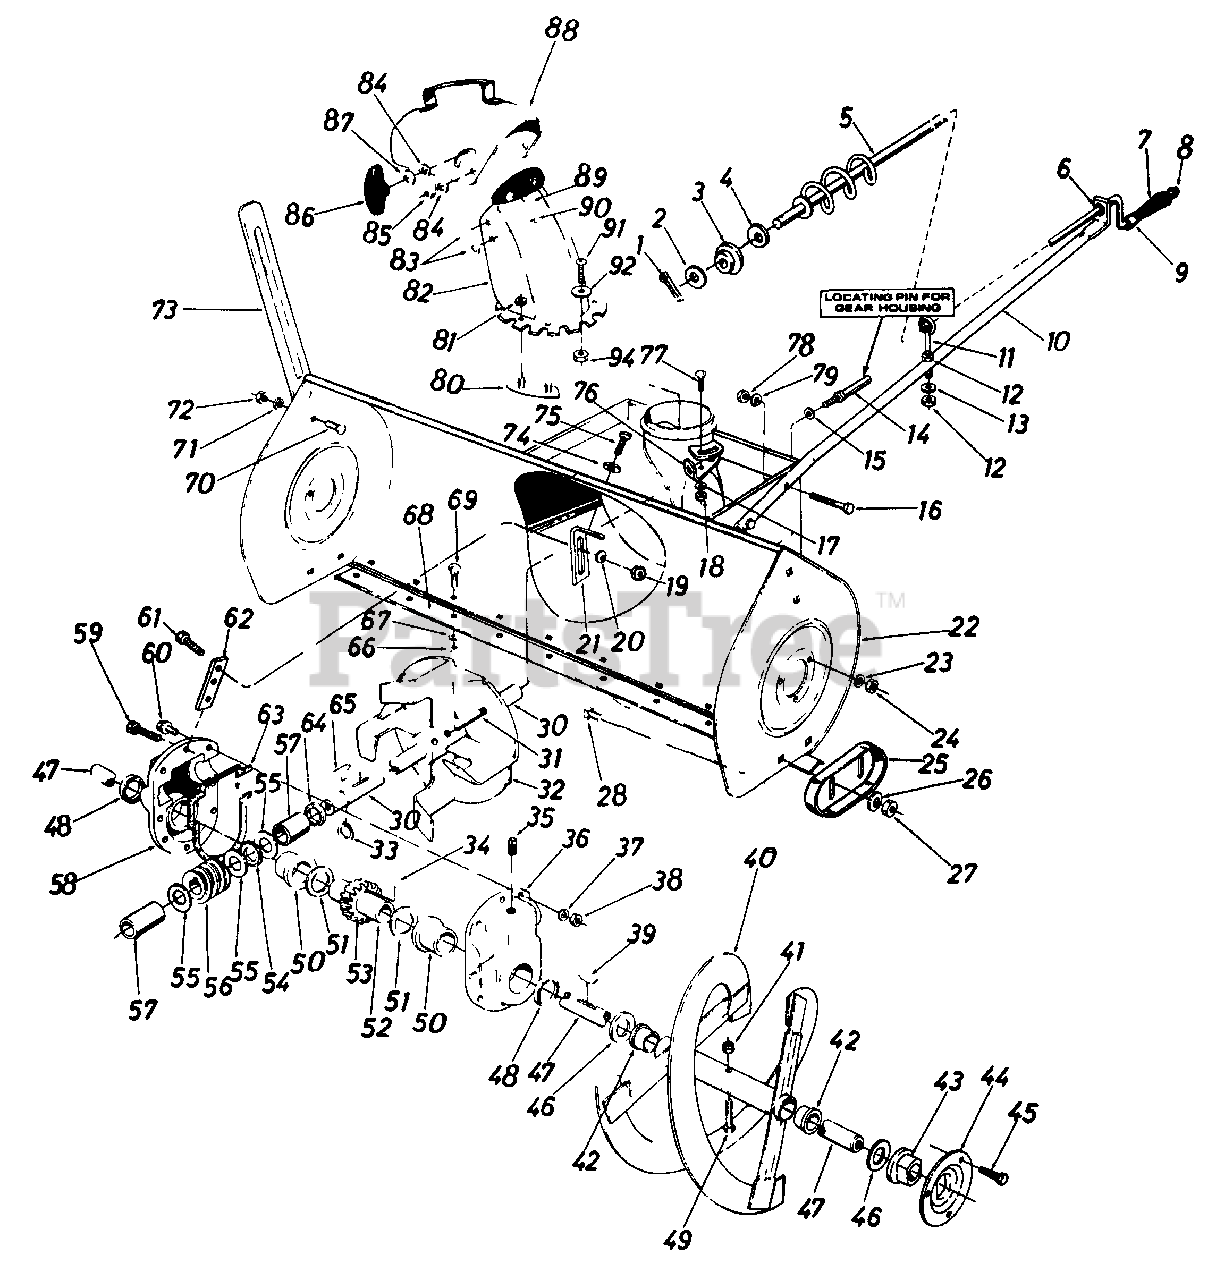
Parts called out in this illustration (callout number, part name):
1	Cotter Pin
2	Fl.-Wash. .39" I.D. x .62" O.D.
3	Plastic Bushing
4	Fl.-Wash. .385 I.D. x .62" O.D.
5	Chute Crank Ass'y.
6	Plastic Bushing
7	Knob Ball 3/8 Dia. Hole
8	Push Nut 3/8" Rod
9	Spacer .385 1. D. x .50" 1. D.
10	Chute Crank Support Tubing
11	Eyebolt
12	Hex Nut 5/16-18 Thd.*
13	Bell. Wash. .345" I.D. x .88" O.D.
14	Stud 3/8-16 x 2.75" Lg.
15	Bell.-Wash. .400" I.D. x .88" O.D.
16	Hex Bolt 3/8-24 x 1.25" Lg.*
17	Bell.-Wash. .345" I.D. x .88" O.D.
18	Hex Nut 5/16-18 Thd.*
19	Hex Nut 1/4-28 Thd.
20	Bell.-Wash. .265" I.D. x .75" O.D.
21	Gear Housing Support Brkt.
22	45 " Snow Blower Housing Ass'y.
23	L.-Wash. 5/16" I.D. *
24	Hex Nut 5/16-18 Thd.*
25	Slide Shoe
26	Bell .-Wash. .400" I . D. x .88 " O.D.
27	Hex Jam Nut 3/8-16 Thd.
28	Carriage Bolt 3/8-16 x .62" Lg.*
30	Blower Axle .875" Dia. x 14.75" Lg.
31	Spring Pin Spir. 5/16" Dia. x 1.75" Lg.
32	Blower Fan Ass'y.
33	Snap Ring For .875" Dia. Shaft
34	#91 Woodr-Key 1/4 x 3/4" Dia. (HDN)
35	Vent Plug
36	Comp. Gear Hsg. Half-L.H.
37	Spr.-Wash. .32" I.D. x .62" O.D.
38	Hex Ins. L.-Nut 5/16-18 Thd.
39	#91 Woodr-Key 1/4 x 3/4" Dia. (HDN)
41	Hex Ins. L.-Nut 5/16-18 Thd.
42	Plastic Bushing
43	Flange Brg. w/ flats l" I.D.
44	Bearing Housing
45	Hex Sems Bolt 5/16-18 x .75" Lg. *
46	Fl.-Wash. 1.00" I.D. x 1.75" O.D.
47	Spiral Axle
48	Flange Bearing 1.503" I.D.
49	Shear Bolt 5/16-18 x 1.75" Lg.
50	Oil Seal 1.50" I.D.
51	Fl.-Wash. 1.50" I.D. x 2.00" O.D.
52	Worm Gear Shaft
53	Double Threaded Worm Gear- 0 L . H .
54	Thrust Brg.-.88" I.D. x 1.44" O.D.
55	Fl. Wash. .88" I.D. x 1.4" O.D.
56	Double Threaded Worm-L.H.
57	Sleeve
58	Complete Gear Hsg. Half-R.H.
59	Hex Bolt 5/16-18 x l.25" Lg.*
60	Hex Bolt 5/16-18 x 1.0" Lg. (Grade 5)
61	Hex Bolt 1/4 28 x .75" Lg.
62	Gear Housing Support Plate
63	Rubber Gasket
64	Oil Seal-.875" I.D.
65	#9 Hi-Pro Key 3/16 x 3/4" Dia. (HT.)
66	Hex Nut 5/16-18 Thd.*
67	L.-Wash. 5/16" I.D.*
68	Shave Plate
69	Carriage Bolt 5/16-18 x 1.00" Lg.
70	Carriage Bolt 5/16-18 x .62" Lg. *
71	L.-Wash. 5/16" I.D.*
72	Hex Nut 5/16-18 Thd.*
73	Guide Blade
74	Bell.-Wash. .345" I.D. x .88" O.D.
75	Hex Wash. Hd. AB Tap Scr 5/16 x .75" Lg.
76	Chute Crank Brkt.
77	Carriage Bolt 5/16-18 x .75" Lg.*
78	Hex Ins. L.-Nut 3/8-24 Thd.
79	L. Wash. 3/8" I.D.*
80	Chute Flange Keeper
81	Hex Cent. L. Nut 1/4-20 Thd.
82	Chute Ass'y. w/ Chute Guard
83	Fl.-Wash. .285" I.D. x 1.25" O.D.
84	Bell.-Wash. .345" I.D. x .88" O.D.
85	Hex Cent. L.-Nut 5/16-18 Thd.
86	Knob Handle
87	Bell.-Wash. .345" I.D. x .88" O.D.
88	Top Chute Ass'y.
89	Carriage Bolt 5/16-18 x 1.00" Lg.*
90	Carriage Bolt 5/16-18 x .62" Lg *
91	Truss l\/lach. Scr. 1/4-20 x .50
92	Fl.-Wash. .285" I.D. x 1.25" O.D.
94	Hex Cent. L-Nut 1/4-20 Thd.
